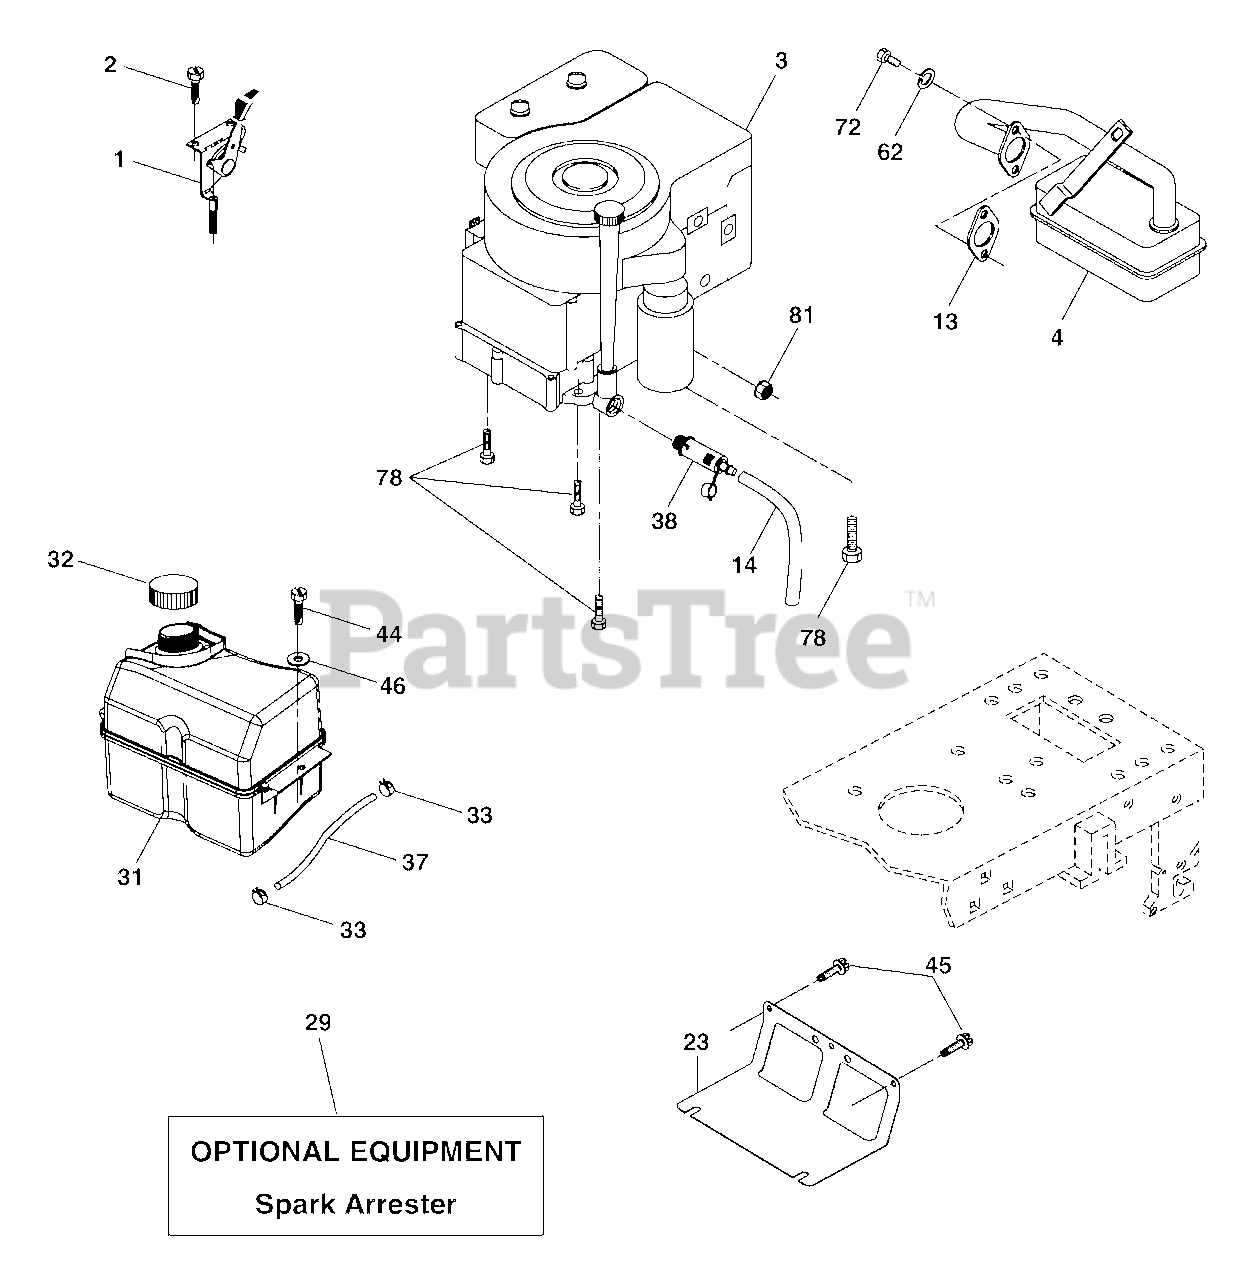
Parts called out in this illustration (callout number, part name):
1	Control, Throttle/Choke
2	10 x 3/4 Single Lead Hex
4	Muffler
13	Muffler Gasket
14	Tube Oil Drain
23	Shield, Browning/Debris Guard
29	Arrester, Spark
31	Tank, Fuel
32	Cap Gauge, Fuel
33	Clamp, Hose Blk
37	Line, Fuel
38	Plug Drain Oil Easy
41	Stem Tank Fuel
44	Screw Hex Wsh Thdrol 1/4-20 x 3/4
45	Screw Hex Wsh Thdrol 3/8-16 x 3/4
46	Washer 9/32 x 7/8 x 16 Ga.
62	Washer Split
72	Screw Hex Hd Cap 5/16-18 x 3/4
78	Screw 3/8-16 x 1-1/4
81	Nut Keps Hex 1/4-20 unc
